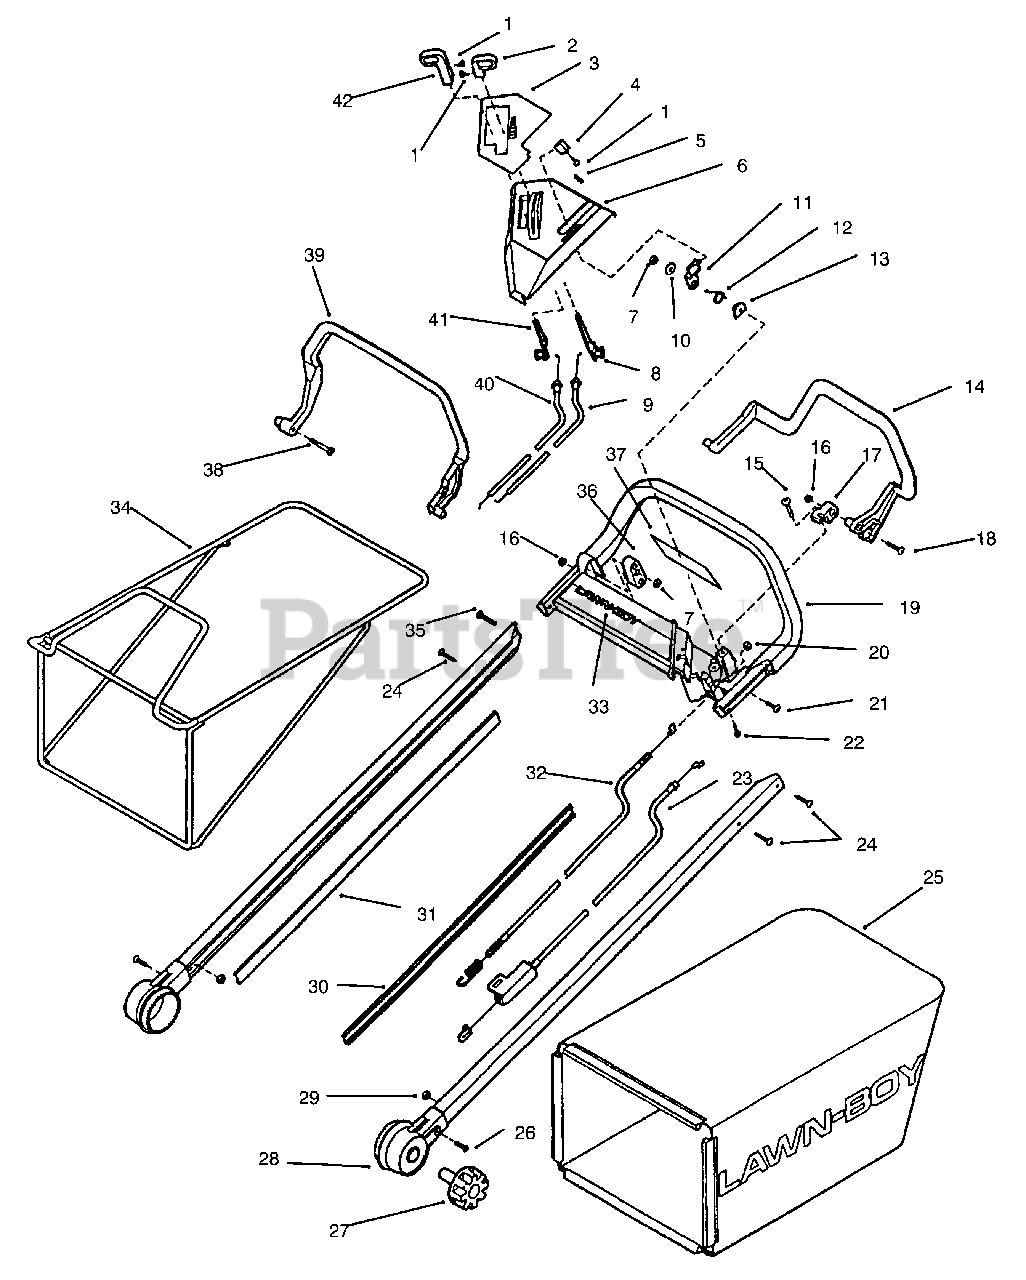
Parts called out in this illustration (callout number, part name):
1	Screw-Set
2	Assembly-Knob, Throttle (Incl. Ref. #1)
4	Assy.-Knob, BBC Latch (Incl. Ref. #1)
6	Assembly-Cover, Upper (Incl. Ref. #3)
8	Lever-Throttle
9	Assembly-Cable, Throttle
11	Lever-Latch, BBc
14	Bail-Self-propelled
17	Pivot-Bail
19	Assembly-Handle & Decal (Incl. Ref. #24,33 & 37)
20	Nut-Cable, Self-propelled
23	Assy.-Cable, BBC
24	Screw-Thread Forming
27	Knob-Mounting, Handle
28	Assembly-Shaft, Handle (Incl. Ref. # 26 & 29)
30	Insert-Handle, Cable Side
31	Insert-Handle
32	Assy.-Cable, Self-propelled
33	Decal-Lawn-Boy
36	Block-Bail
37	Decal-Warning
39	Bail-Brake, Engine
40	Assy.-Cable, Gear Select
41	Lever-Gear, Select
42	Assembly-Knob (Incl. Ref. #1)
